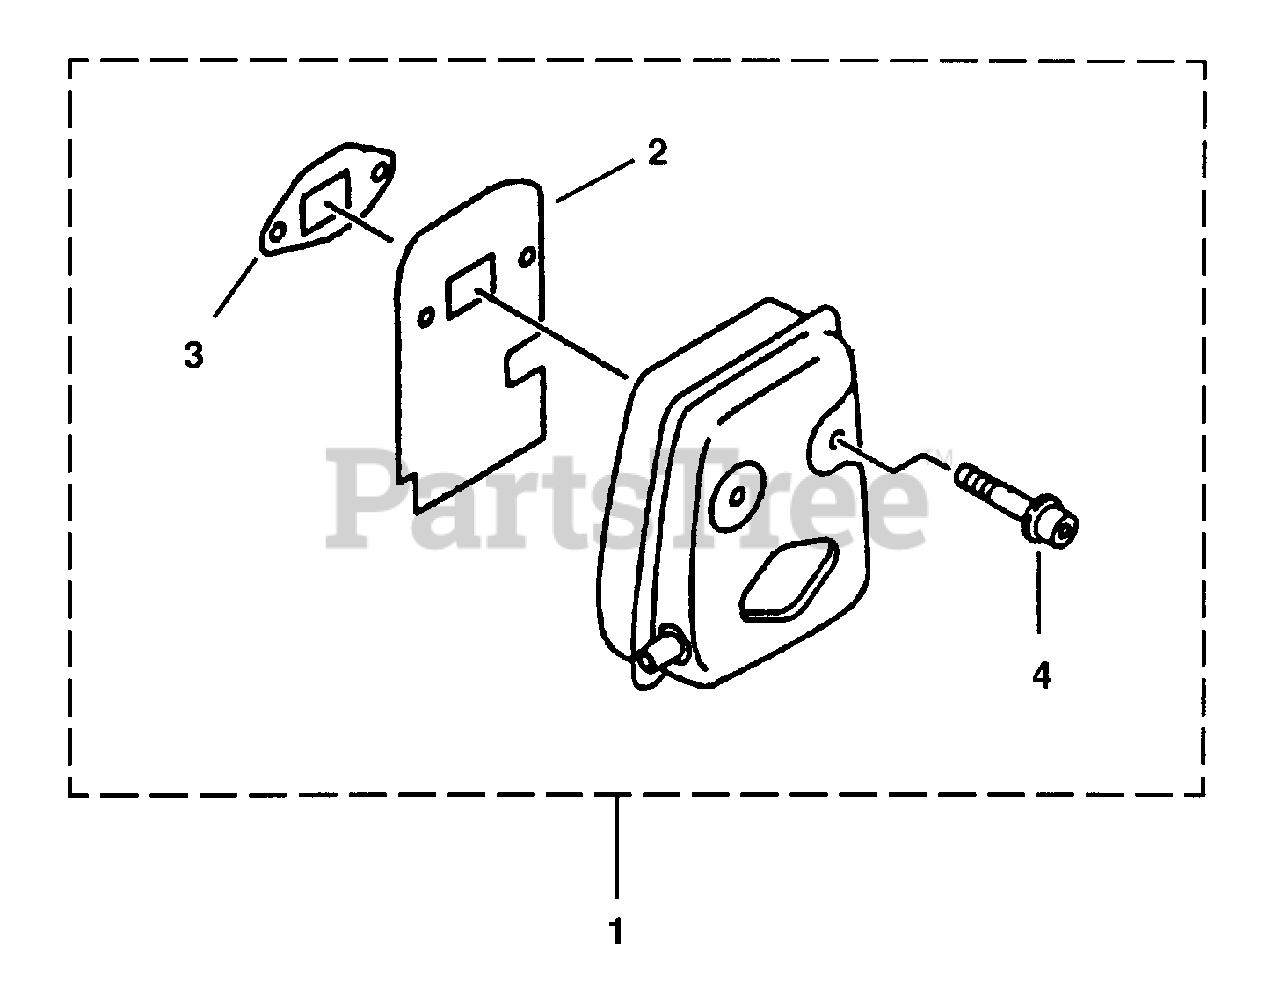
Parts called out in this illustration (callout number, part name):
1	MUFFLER ASSEMBLY
2	INSULATOR-Muffler
3	GASKET-Muffler
4	SCREW-Socket Hd (M5 x 40 W)
